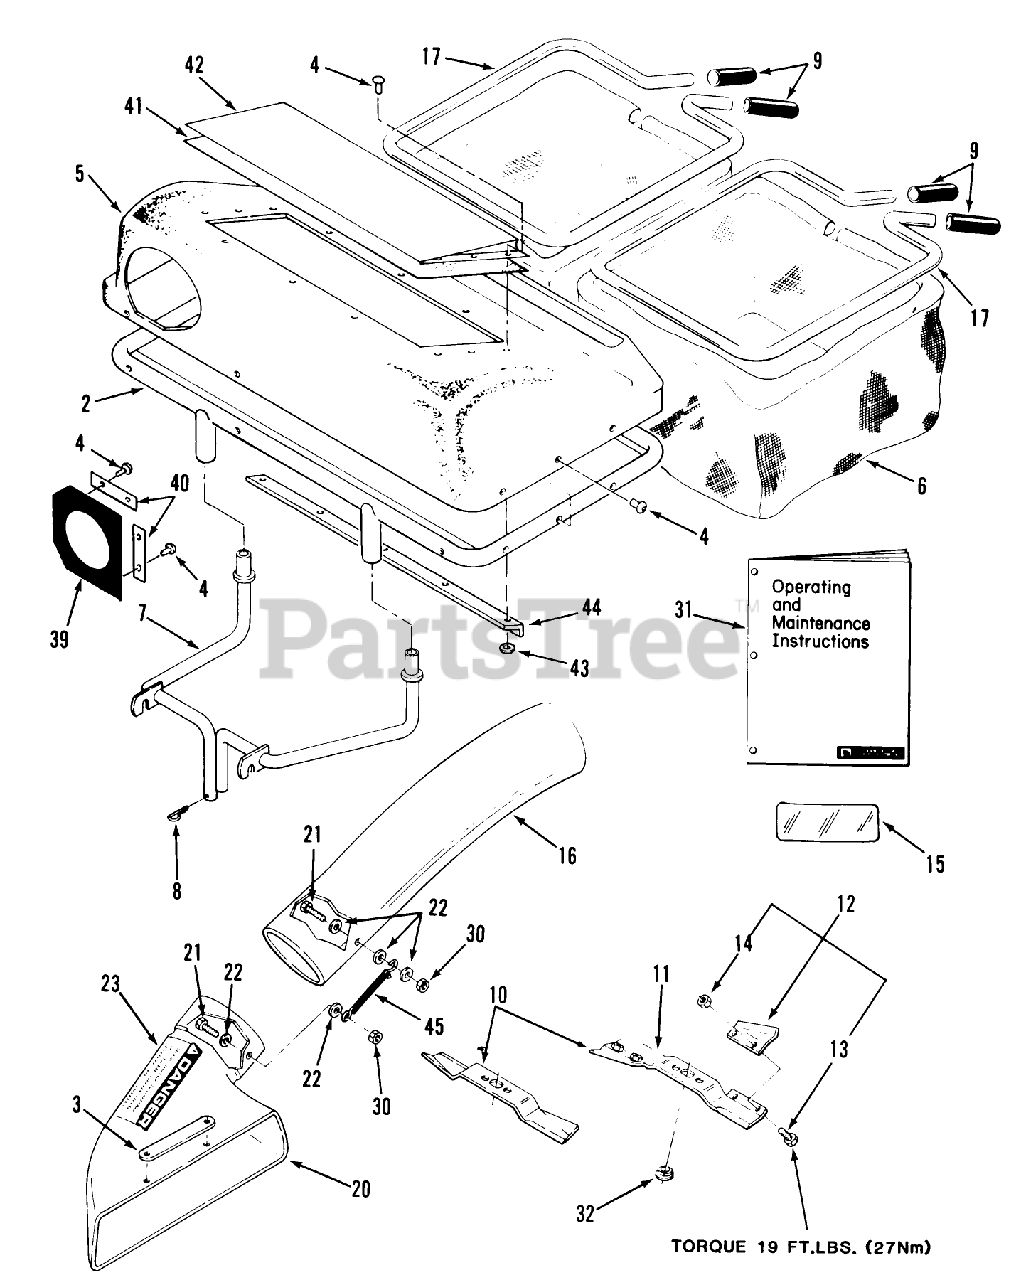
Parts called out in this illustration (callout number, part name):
3	PLATE-ELBOW *B
4	RIVET-BLIND
8	Hairpin
9	GRIP
10	KIT-BLADE (SERVICE)
11	ASSY-HI LIFT BLADE
12	S/A 37 LIFT TAB KIT
13	BOLT 5/16-18X5/8
14	NUT-HEX
15	DECAL-OVERLAY
23	DECAL-DANGER
31	Operating and Maintenance Instructions
32	SPACER BLADE
